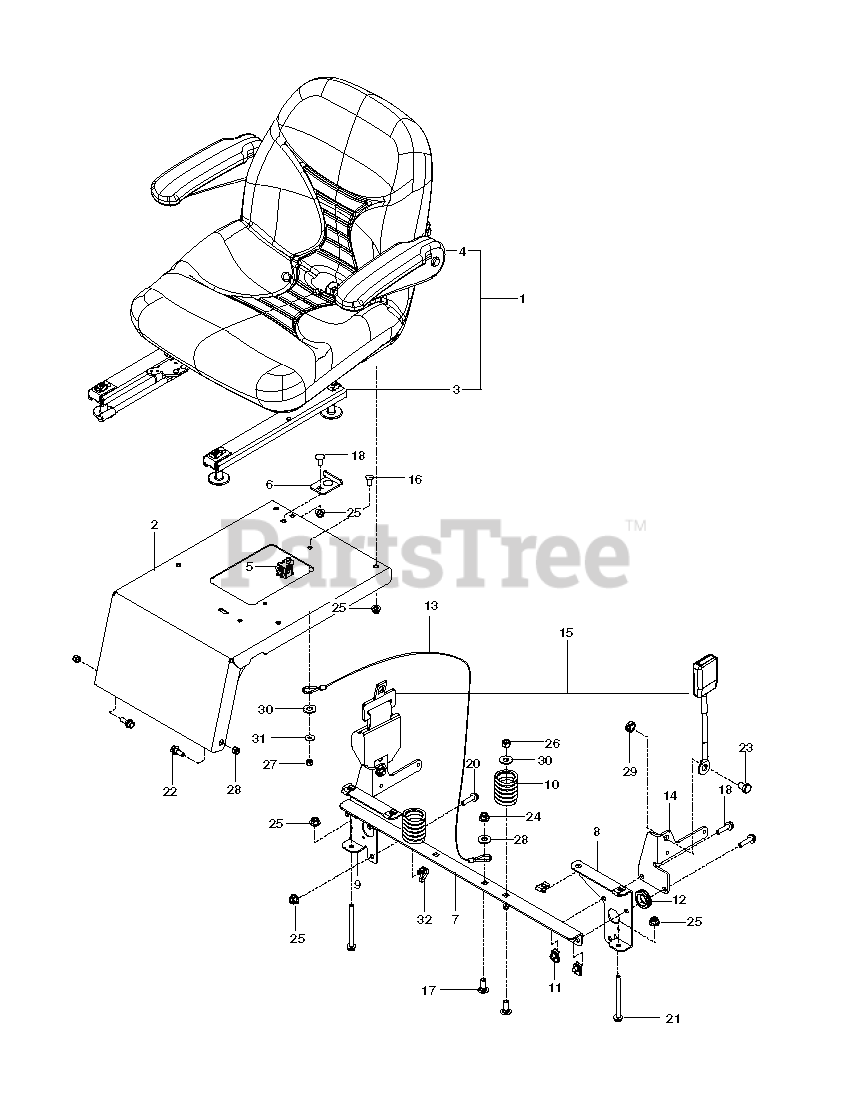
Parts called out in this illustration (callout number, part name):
1	SEAT
2	KIT.SEAT.MOUNT.W/DECAL
3	TRACK ADJUSTMENT KIT
4	ARMREST KIT, LT SQUARE END
5	SWITCH.SNAPMOUNT.NC
6	STOP, SEAT - BLACK
7	SUPPORT, SEAT
8	SUPPORT, LT, BLK
9	SUPPORT, RT, BLK
10	SPRING, SEAT
11	U-CLIP 5/16-18 NUT RETAINER
12	RUBBER GROMMET
13	SEAT LANYARD
14	MOUNT, SEAT BELT, BLACK
15	Seat Belt, Retractable
16	RHSNB 1/4C X 3/4
17	RHSNB 3/8C X 1
18	RHSNB 5/16-18 X 3/4
19	HHFS 5/16-18 X 1.25 TPBLT GD 5
20	HHFS 5/16-18 X 3/4
21	HHFS 5/16-18 X 3 3/4
22	SB 5/16-18 HEX HD GD5, BLK ZN
23	HCS 7/16-20 X .75 GD 5
24	NUT 3/8-16 HEX FLG NYLOC ZD
25	5/16-18 NYLOC FLANGE NUT
26	NUT 3/8-16 NYLOC
27	RP_NUT 1/4-20 NYLOC
28	NUT 5/16 NYLOC
29	NUT HEX 7/16F LOCK RP
30	RP WASHER 3/8 FLAT
31	WASHER 1/4 FLAT
32	TIE WRAP, 8-3/8", W/CLIP
